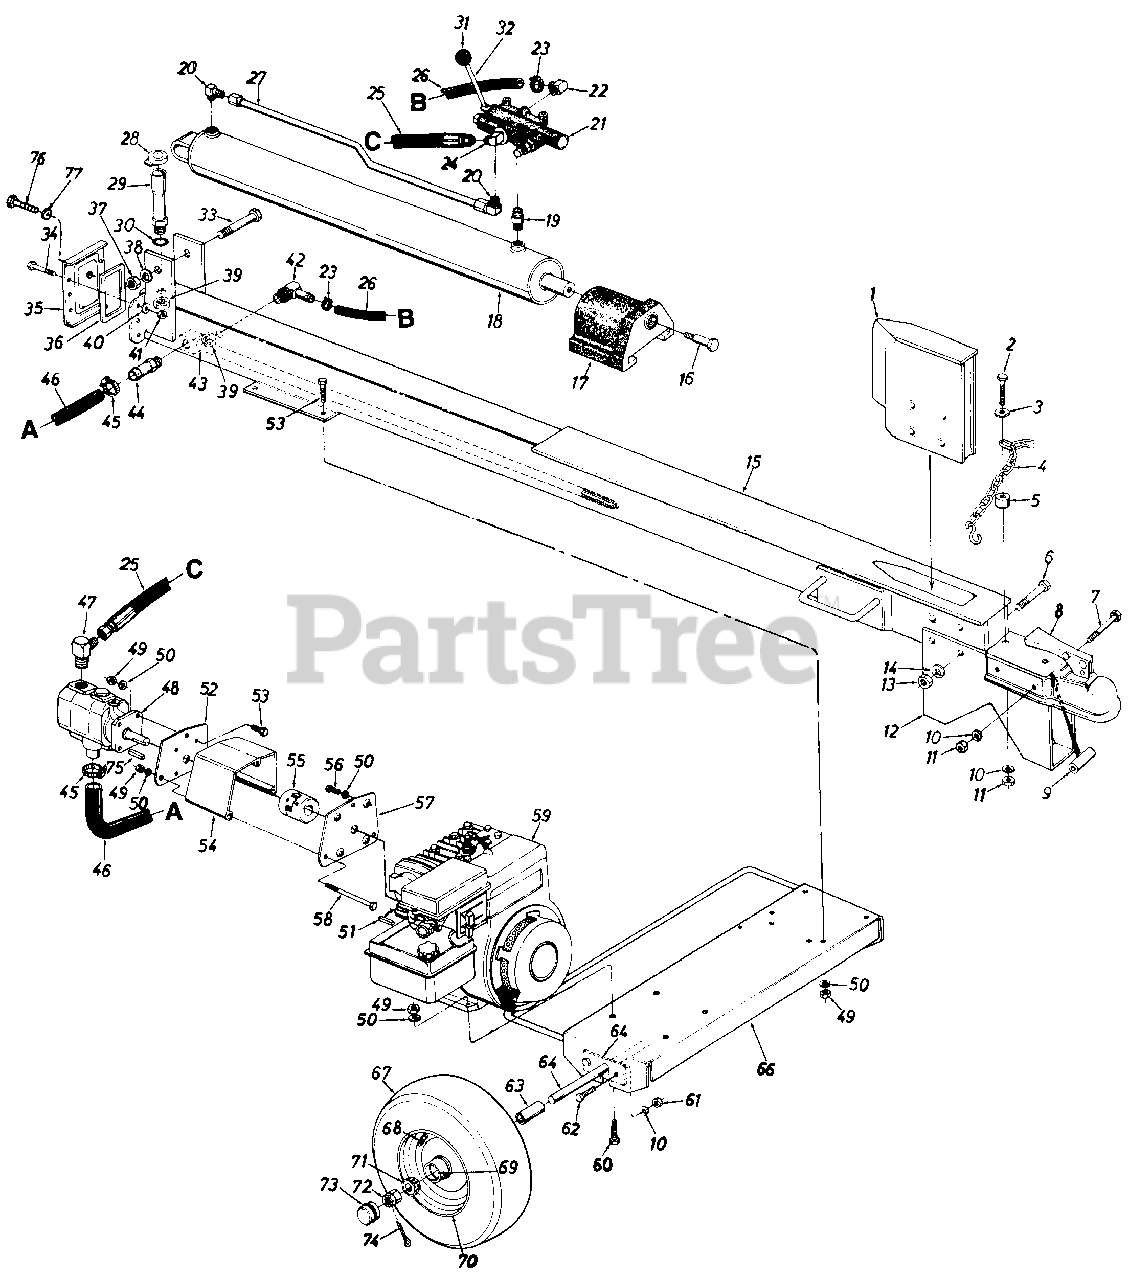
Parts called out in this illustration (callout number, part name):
1	Wedge Ass'y.
2	Hex Bolt 3/8-16 x 1.5" Lg. (Grade 5)
3	Fl-Wash. .375" I.D. x .87" O.D.
4	Chain-Tow Hitch
5	Spacer .38" I.D. x .625" O.D.
6	Hex Bolt 5/8-18 x 3.5" Lg.
7	Hex Bolt 3/8-16 x 3.25" Lg. (Grade 8)
8	Tow Hitch Ass'y.
9	Spacer .375" I.D. x .625" O.D.
10	L-Wash. 3/8"1 I.D.
11	Hex Nut 3/8-16 Thd. (Grade 5)
12	Beam Stand
13	Hex Nut 5/8-18 Thd.
14	L-Wash. 5/8" I.D.
15	452/N Oil Tank Ass'y.
16	Shld. Bolt .62" Dia. x .475"
17	Pusher Plate
18	Hydraulic Cylinder
19	Pipe Nipple 1/2" NPT x 2" Lg.
20	90ø Solid Male Adapter
21	Control Valve
22	Return Elbow
23	Adjustable Hose Clamp
24	90ø Solid Male Adapter
25	High Pressure Hydraulic Hose 29.5" Lg.
26	Return Hose 3/4" I.D. x 23-1/2" Lg.
27	Metal Pressure Tube
29	Filler Tube Ass'y.
30	"O"-Ring.92" I.D.
31	Ball Knob
32	Control Handle
33	Hex Bolt 3/4-10 x 4.5" Lg.
34	Hex Bolt 5/16-18 x 1.5" Lg.
35	Beam End Plate
36	Gasket
37	Hex Nut 3/4-10 Thd.
38	L-Wash. 3/4" I.D.
39	Hex Nut 1-1/16-12 Thd.
40	Fl-Wash. .34" I.D. x .68" O.D.
41	Hex L-Nut 5/16-18 Thd.
42	90ø Adapter 3/4" Hose
43	Strainer Tube Ass'y.
44	Adapter 1" x 1-1/16-12 Thd.
45	Hose Clamp 5/8"
46	Suction Hose 1n I.D.
47	90ø Adapter
48	Two Volume Pump
49	Hex Nut 5/16-24 Thd.
50	L-Wash. 5/16" I.D.
51	Sq. Key 3/16 x .75" Lg.
53	Hex Bolt 5/16-24 x 1.0" Lg.
54	Coupling Shield
55	Flexible Coupling
56	Hex Bolt 5/16-24 x .62" Lg.
58	Hex Bolt 5/16-24 x 4 on Lg.
59	Engine
60	Hex Bolt 5/16-24 x 1.75" Lg.
61	Hex Nut 3/8-24 Thd.
62	Hex Bolt 3/8-24 x 1.0" Lg.
63	Spacer .75" I.D. x 1.12" O.D.
64	Axle Assembly
66	Engine Frame Ass'y.
68	Air Valve
69	Bearing Seal
71	Roller Bearing w/Race
72	Hex Slotted Nut 3/4-16 Thd.
73	Hub Cap
74	Cotter Pin 5/32" Dia.
75	Hi-Pro Key 1/8" x 1/2" Lg.
76	Hex TT-Tap Scr. 5/16-18 x .62" Lg.
77	Gasket Washer 5/16" I.D.
